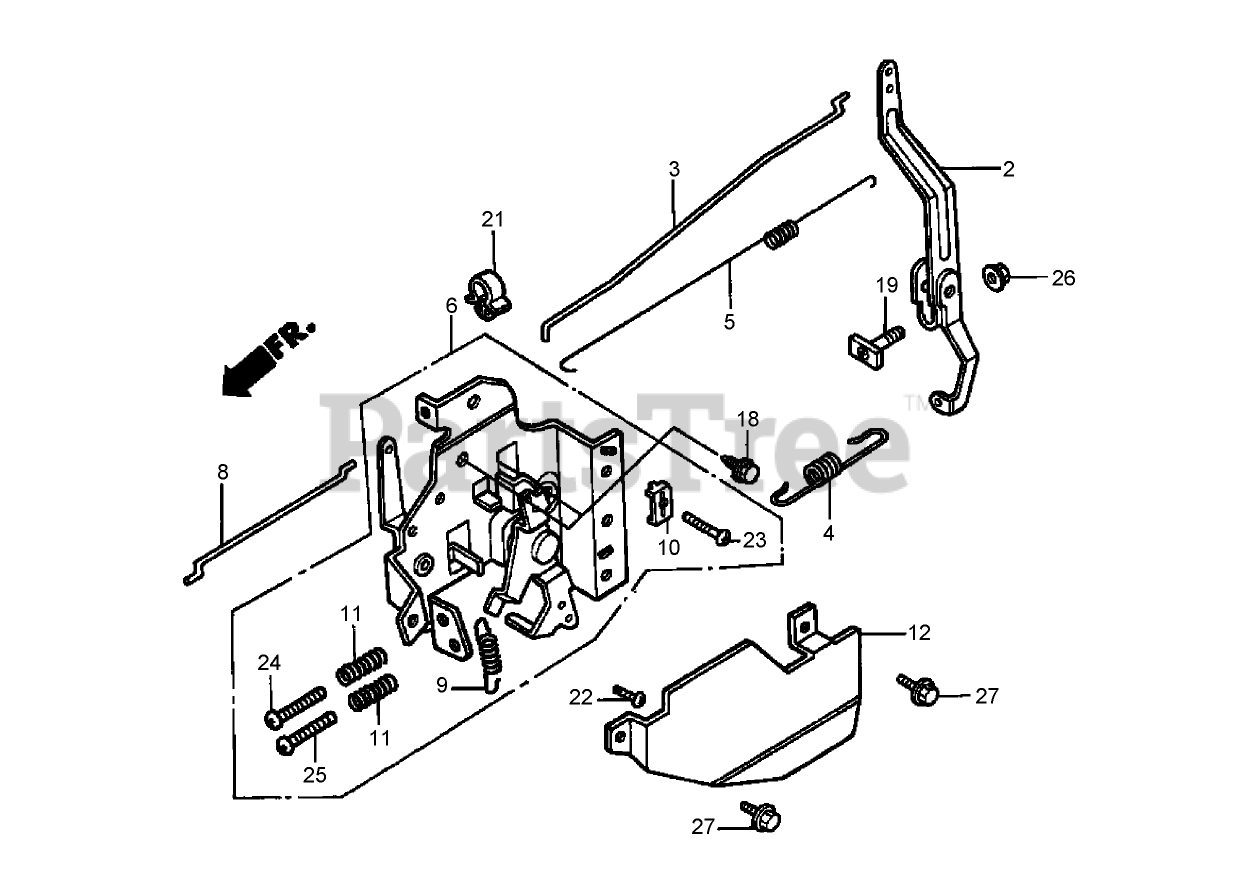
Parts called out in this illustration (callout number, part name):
2	Arm-Governor
3	Rod-Governor
4	Spring-Governor (STD)
5	SPRING-RETURN, THROTTLE
6	CONTROL ASM
8	Rod-Choke
9	Spring-Lever
10	Holder-Cable
11	SPRING-ADJUSTING, CONTROL
12	Protector-Control
18	BOLT-FLANGE (6X12) (C T200)
19	BOLT-ARM, GOVERNOR
21	CLIP-HARNESS, WIRE
22	Screw-Pan (4X8)
23	Screw-Pan (5X16)
24	Screw-Pan (5X20)
25	Screw-Pan (5X28)
26	NUT-FLANGE (6 mm)
27	Bolt-Flange (6X10)
